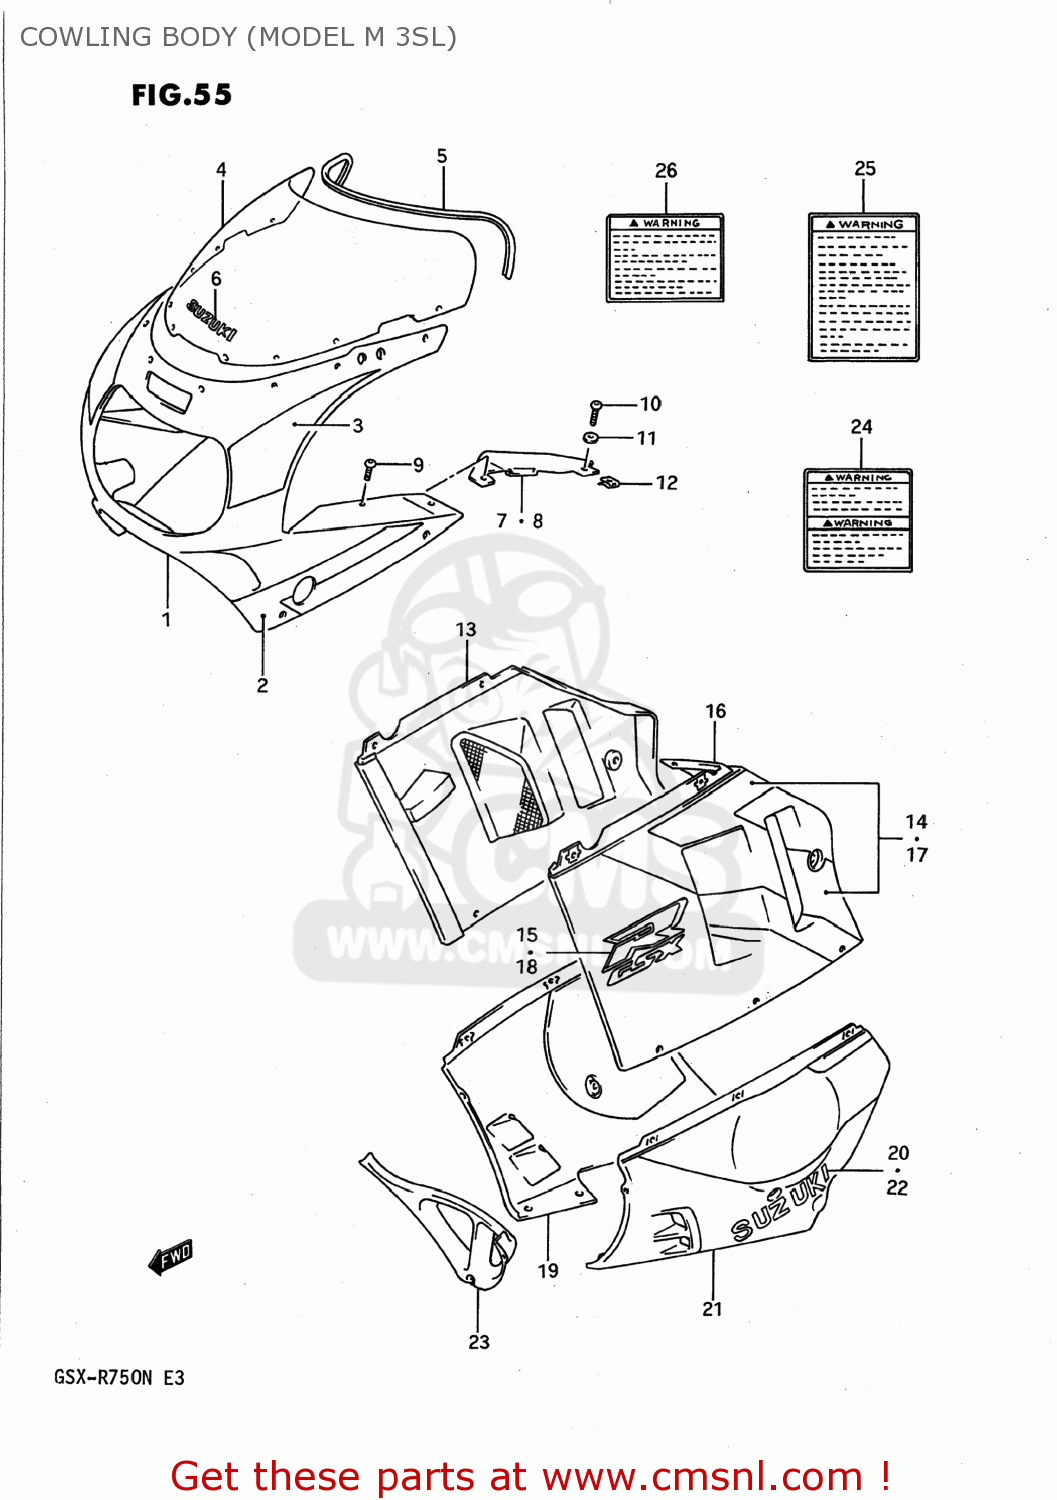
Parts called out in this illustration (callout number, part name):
1	BODY ASSY,COWLING
2	TAPE SET,COWLING
3	TAPE SET,COWL UPR FR
4	SCREEN SET,WIND
5	MOLDING,WINDSCREEN
6	EMBLEM,SUZUKI(WHITE)
7	PANEL,COWLING UPR,R
8	PANEL,COWLING,UPPER,LEFT
9	SCREW(5X10)
10	SCREW(5X14)
11	WASHER(5.2X11X1)
12	NUT
13	COVER COMP,COWLING SIDE,RIGHT
14	TAPE SET,COWLING SIDE
15	EMBLEM,COWLING SIDE
16	COVER COMP,COWLING SIDE,LEFT
17	TAPE SET,COWLING SIDE
18	EMBLEM,COWLING SIDE
19	COWLING COMP,UNDER,RIGHT
20	EMBLEM,SUZUKI
21	COWLING COMP,UNDER,LEFT
22	EMBLEM
23	COWLING,UNDER,CENTER (W
24	LABEL (WARNING)
25	LABEL (WARNING SCREEN)
26	LABEL
